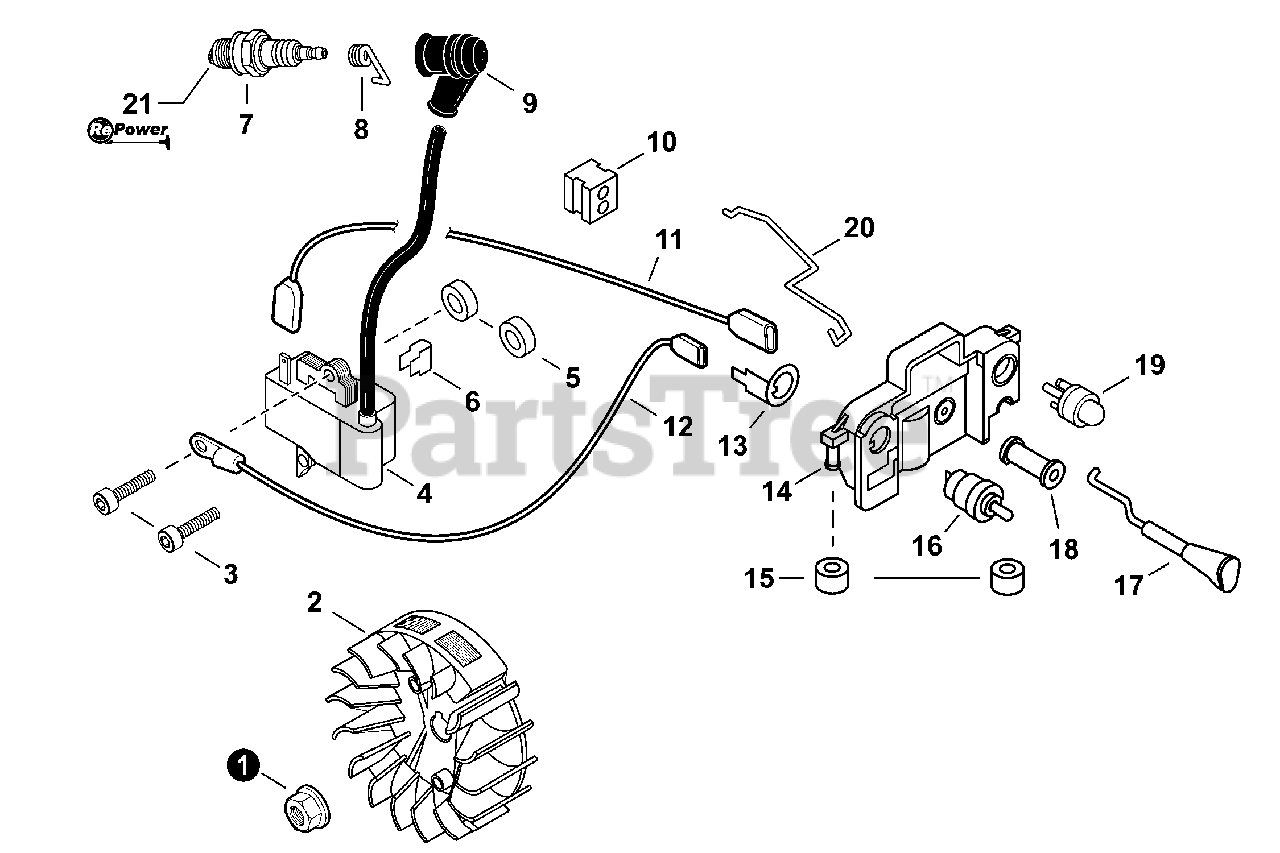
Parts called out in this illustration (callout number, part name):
1	NUT, FLANGE M8
2	FLYWHEEL
3	BOLT 5×20
4	COIL, IGNITION
5	WASHER 5.2×12×3
7	SPARK PLUG - BPM8Y
8	TERMINAL, SPARK PLUG
9	CAP, SPARK PLUG
10	GROMMET, LEAD
11	LEAD - IGNITION L= 172
12	LEAD - GROUND L= 140
13	TERMINAL, GROUND
14	BRACKET, SWITCH
16	SWITCH, ON-OFF
17	ROD, CHOKE
18	GROMMET, CHOKE
19	BULB, PURGE
20	ROD, THROTTLE
21	TUNE-UP KIT - REPOWER
